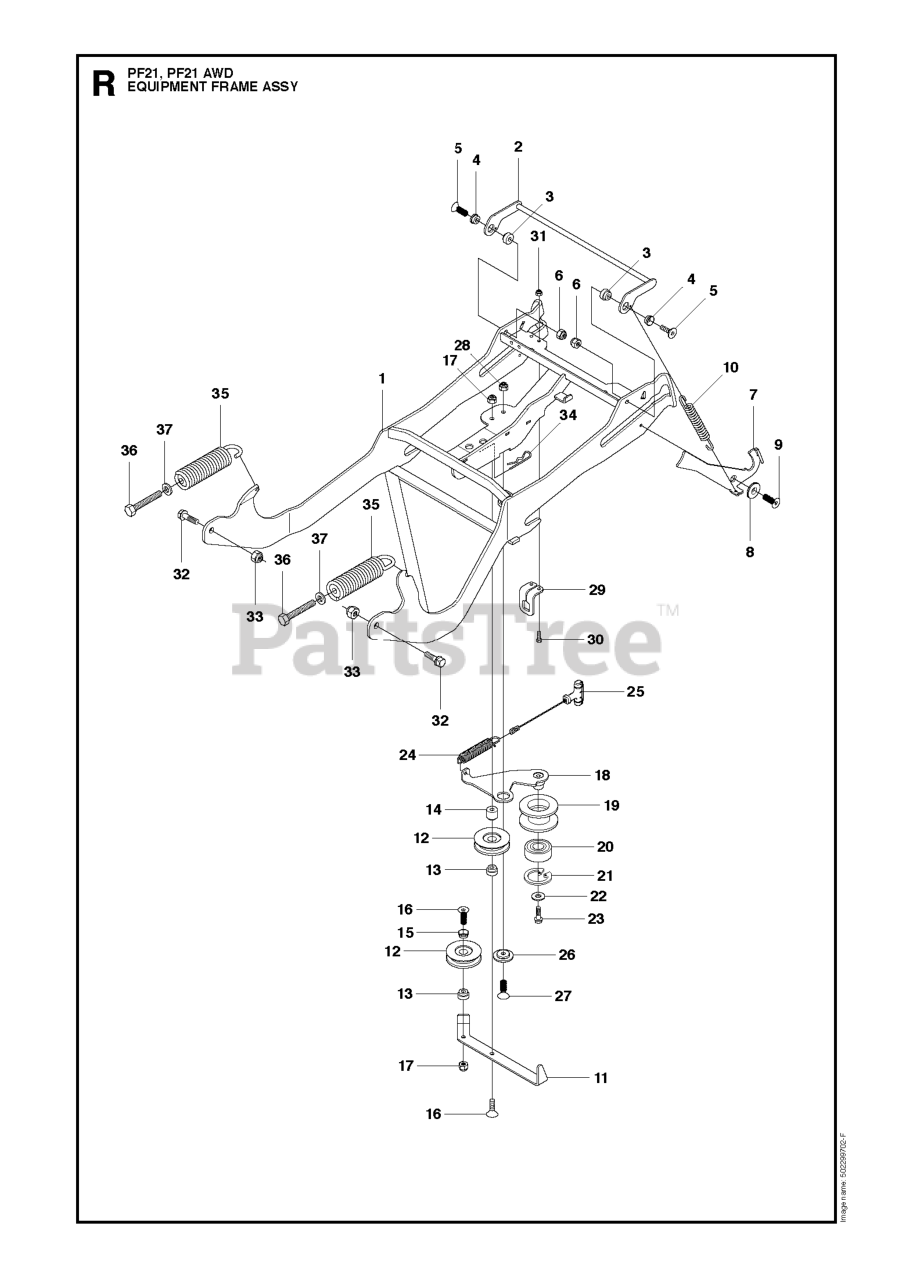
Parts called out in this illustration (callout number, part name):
6	LOCKNUT M8
8	SPACER
9	SCREW IHCSFM
12	PULLEY ASSY
17	LOCKNUT M8
19	%PULLEY
20	BALL BEARING 6004-2RS1
21	RETAINING RING
26	WASHER
28	LOCKNUT M8
30	BOLT FLANGE - M6X20
31	LOCKNUT M6
37	WASHER
